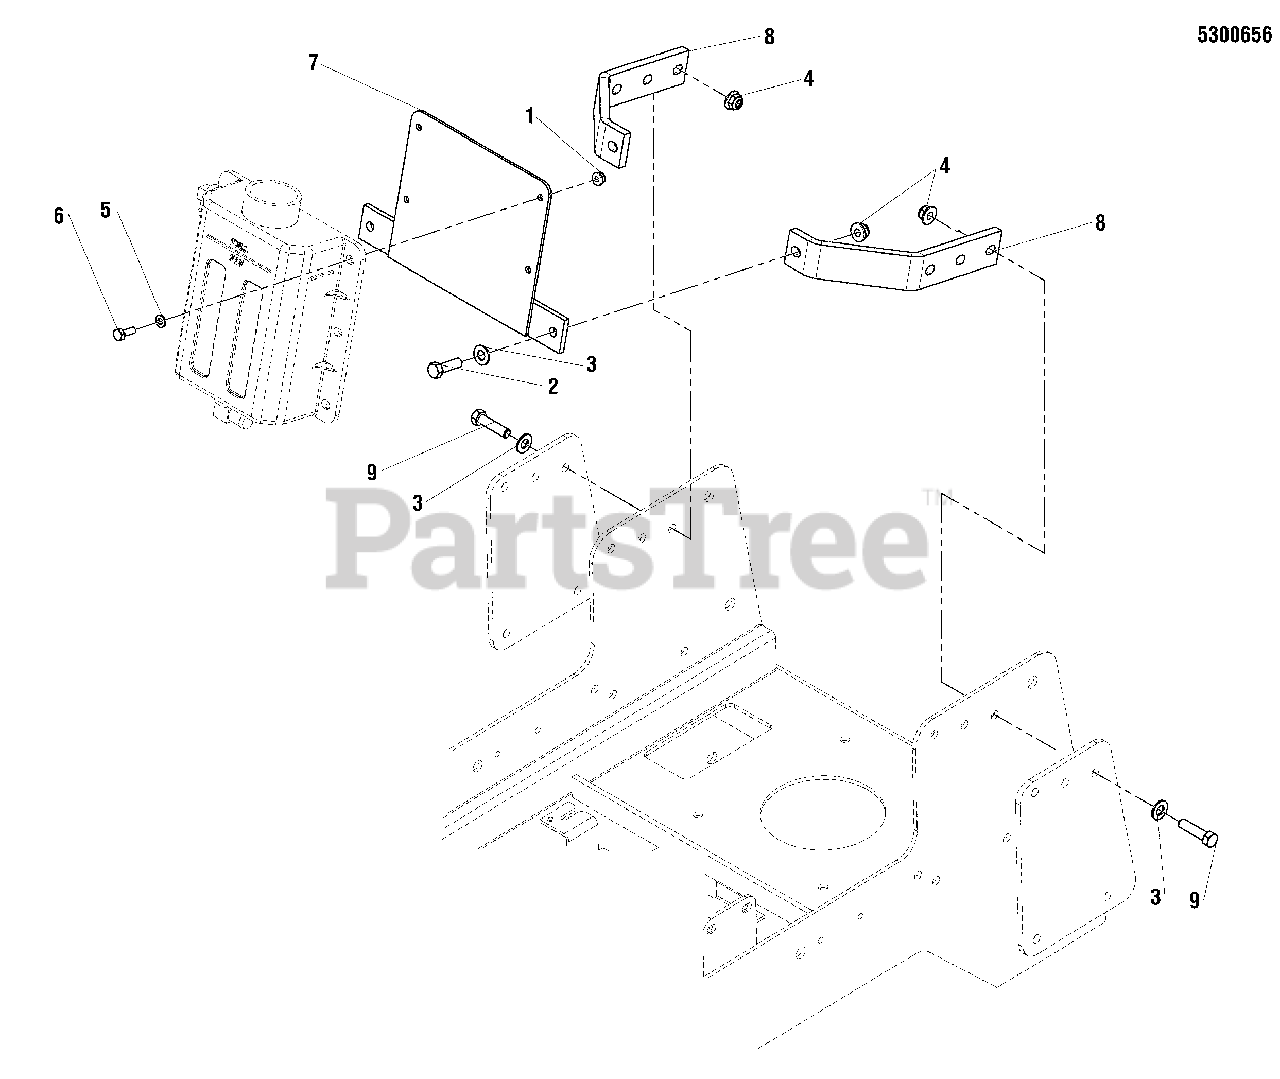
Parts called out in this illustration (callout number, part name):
1	NUT, 1/4-20 HEX NYLOCK FLANGE (5025391)
2	BOLT, 3/8-16 X 1-1/4 GD5
3	WASHER, 3/8 SAE
4	NUT, 3/8-16 HEX NYLOCK FLANGE
5	BOLT, 1/4-20 X 3/4 GD5 YZ
6	WASHER, 1/4 SAE (5025154)
7	WELD, HYD TANK MOUNT
8	BRACKET, HYDRAULIC TANK
9	BOLT, 3/8-16 X 1-1/2 GD5 YZ
